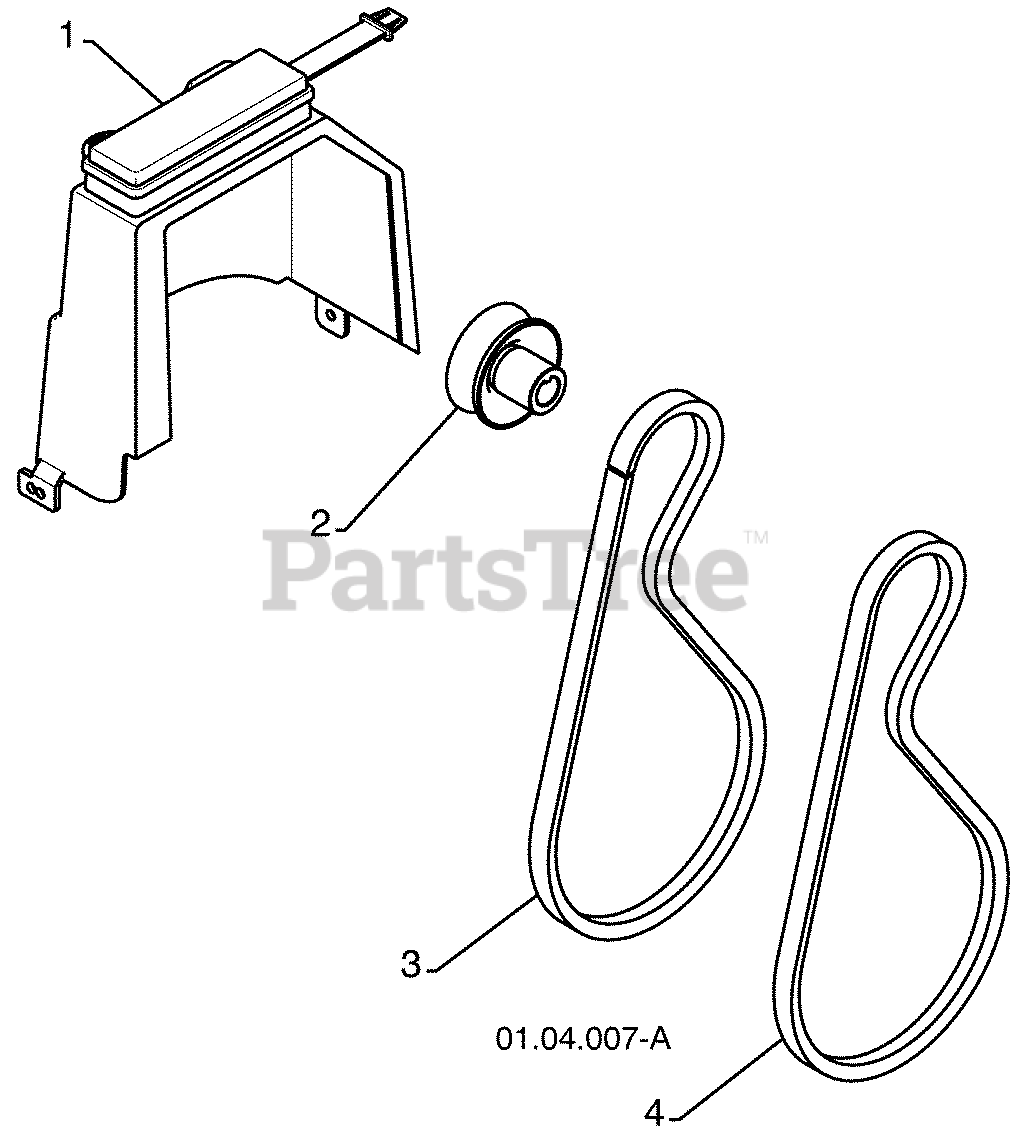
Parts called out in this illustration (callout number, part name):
1	COVER.ASM.BELT/STORAGE
2	PULLEY, ENGINE IMPELLER DRIVE
3	V-BELT TRACTION 34.25
4	BELT.V.IMPELLER.DRIVE
